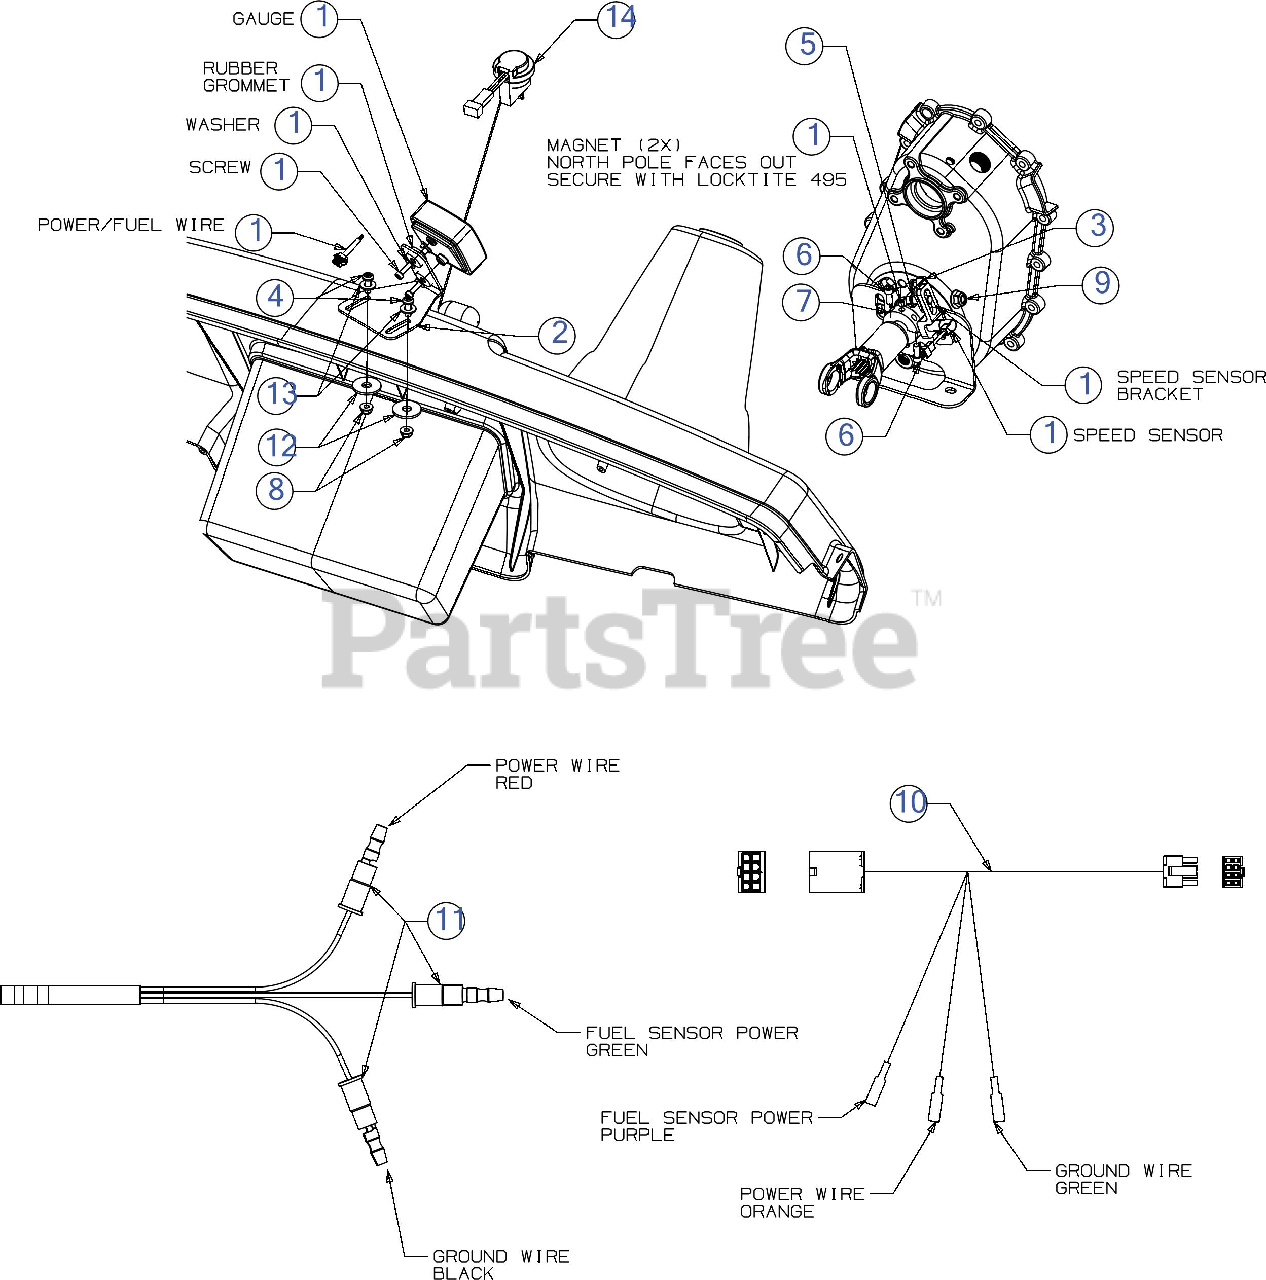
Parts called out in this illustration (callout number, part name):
1	UV GAUGE ASSEMBLY
4	SCREW 1/4-20X.75
5	SCREW 3/8-16 x .880 GR5
6	SOCKET 1/4-20X.62 GR-8
7	SPLIT COLLAR 25/32
8	FLANGE LOCK NUT
10	UV SPEED HARNESS
11	MOLEX CONNECTOR
12	FLAT WASHER
13	FLAT WASHER
14	FUEL SENSOR LEVEL
